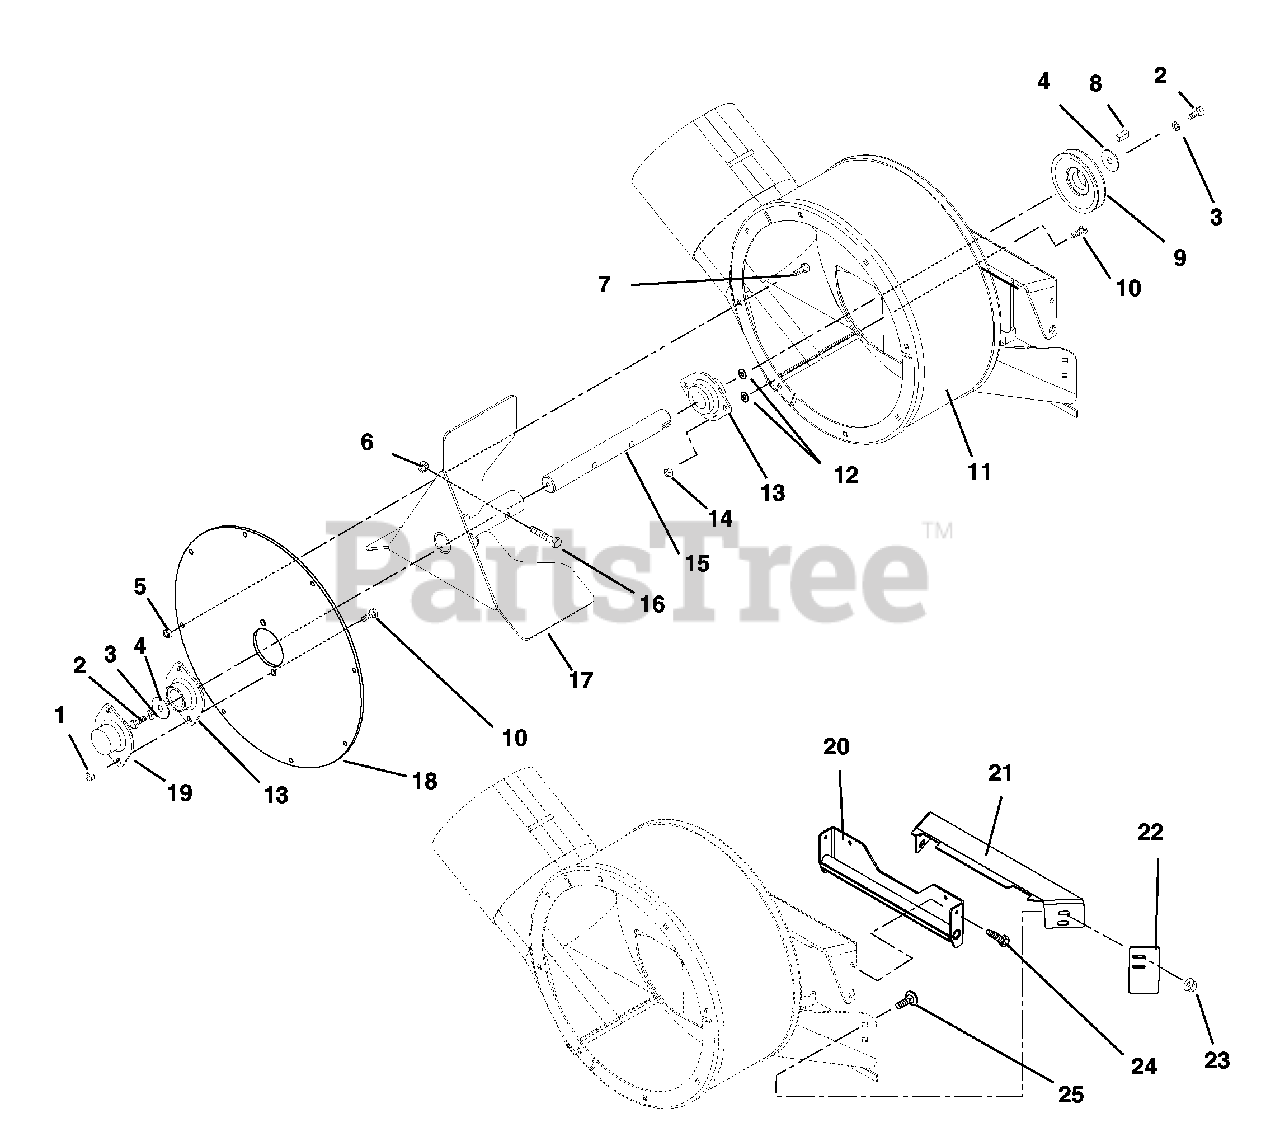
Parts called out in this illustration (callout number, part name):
1	Nut-Locking-Nylon .312-18
2	Bolt-Hex .25-20 x .75 Grade 5
3	Washer-Locking .25 x .062 Regular
4	Washer-Flat-Steel .265 x 1.370 x .179
5	Nut-Locking-Top-Flange .25-20
6	Nut-Locking-Center .31-18
7	Bolt-Round Head Square Neck .25-20 x .50
8	Key-Square .25 x .38 x .25
9	Pulley-Driven 3.50 Dia.
10	Bolt-Hex .31-18 x 1.00 Grade 5
11	Weldment, Blower Housing
12	Washer-Flat-STL .312 x .734 x .06
13	Bearing-2 Bolt x 1.00 Shaft
14	Nut-Locking-Top-Flange .31-18
15	Shaft-Impeller
16	Bolt-Hex .31-18 x 1.75 Grade 5
17	Impeller Complete
18	Cover-Bearing Support
19	Cover-Bearing
20	Weldment, Blower Mount
21	Guard, Pump Inlet
22	Bar, Extension
23	Nut-Locking-Top-Flange .25-20
24	Screw-Tapping .25-20 x .50 Hex Washer Head Thread Rolling
25	Bolt-Round Head Square Neck .25-20X.75 Grade 5
